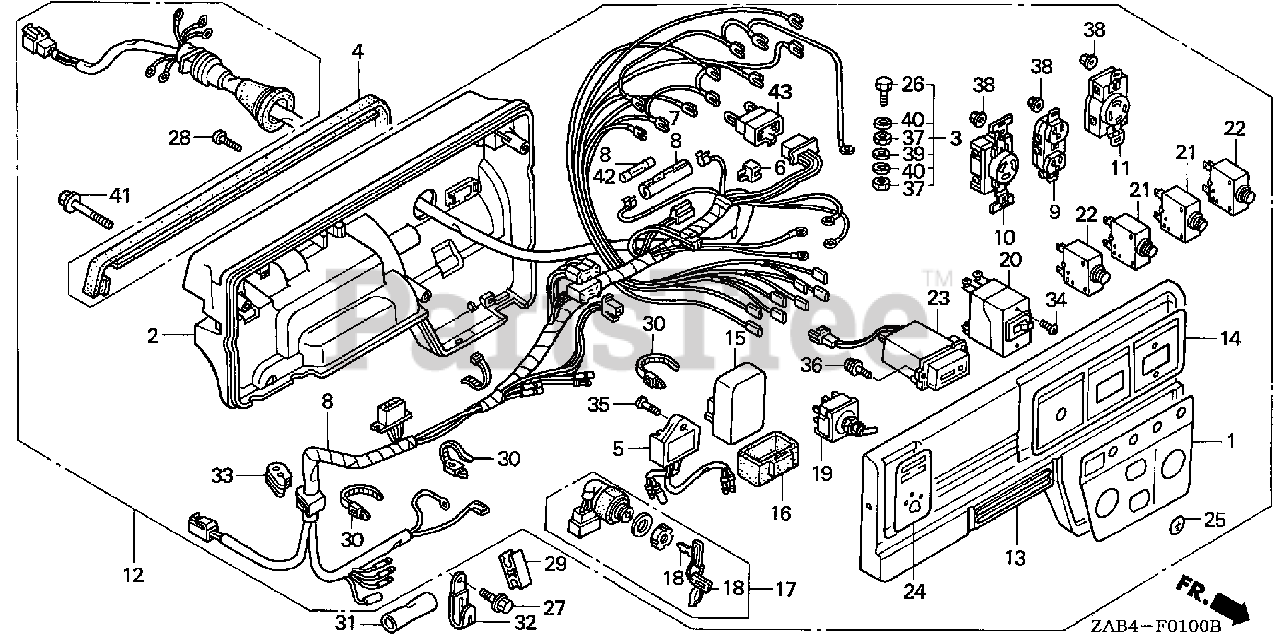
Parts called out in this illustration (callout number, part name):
1	MARK, A.C. OUT
2	CASE, CONTROL *R280* (POWER RED)
3	TERMINAL SET, GROUND
4	RUBBER, CONTROL
5	RECTIFIER ASSY., REGULATOR
7	CASE, FUSE CONNECTOR
8	WIRE HARNESS ASSY., CONTROL
9	RECEPTACLE (20A/125V)
10	RECEPTACLE (3-PRONG) (30A/125V)
11	RECEPTACLE (30A-125/250V)
12	BOX ASSY., CONTROL *R8* (BRIGHT RED)
13	PANEL, CONTROL *R8* (BRIGHT RED)
14	MARK, SWITCH PANEL
15	UNIT, VALVE CONTROL
16	CUSHION, VALVE CONTROL UNIT
17	SWITCH ASSY., COMBINATION
18	KEY
19	SWITCH ASSY., VOLT CHANGE
20	BREAKER, CIRCUIT (23A)
21	PROTECTOR, CIRCUIT (20A)
22	PROTECTOR, CIRCUIT (30A)
23	METER ASSY., HOUR
24	MARK, ENGINE SWITCH
25	MARK, GROUND
26	BOLT, HEX. (6X28)
27	BOLT, FLANGE (6X12) (CT200)
28	SCREW, GLOVE BOX
29	CLIP, TUBE
30	TIE, CABLE
31	TUBE, CORD
32	CLIP, WIRE HARNESS
33	GROMMET, TUBE
34	SCREW, PAN (4X6)
35	SCREW, PAN (6X20)
36	SCREW-WASHER (5X16)
37	NUT, HEX. (6MM)
38	NUT, FLANGE (4MM)
39	WASHER, PLAIN (6MM)
40	WASHER, SPRING (6MM)
41	BOLT, FLANGE (6X40)
42	FUSE B (10A)
43	CONNECTOR ASSY. (8P RED)
